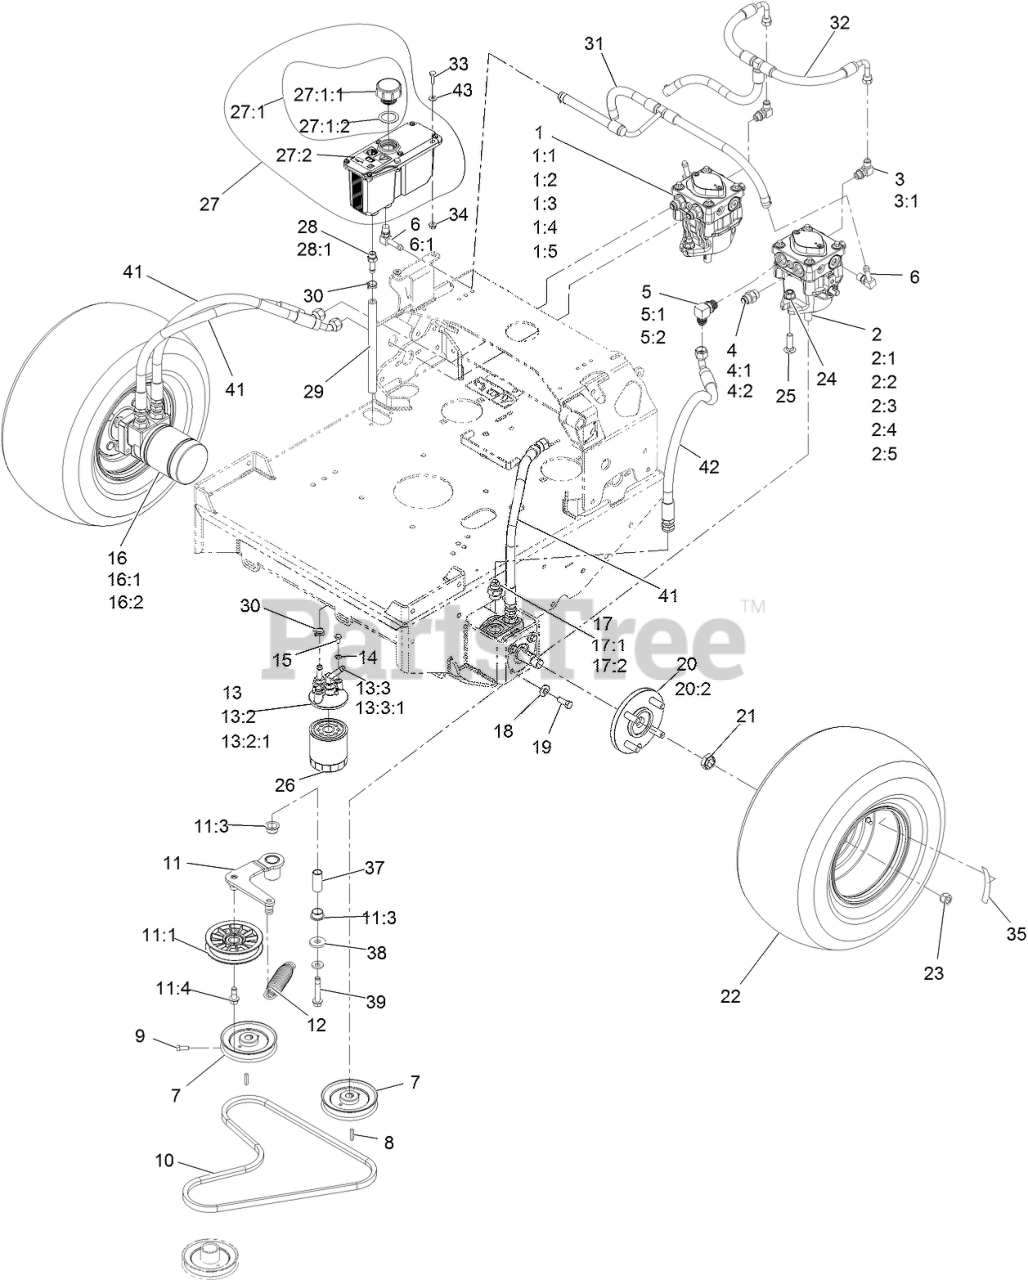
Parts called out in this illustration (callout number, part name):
1	PUMP-HYD PE RH TTH
1:1	INPUT SHAFT KIT
1:2	BEARING-THRUST
1:3	CYLINDER BLOCK KIT
1:4	SEAL OVERHAUL KIT
1:5	KIT, 10CC PUMP KIT
2	PUMP-HYD PE LH TTH
2:1	INPUT SHAFT KIT
2:2	BEARING-THRUST
2:3	CYLINDER BLOCK KIT
2:4	SEAL OVERHAUL KIT
2:5	KIT, 10CC PUMP KIT
3	FITTING-ELBOW, 90 DEG
3:1	O-RING
4	FITTING-STRAIGHT
5	FITTING-90 DEG
6	FITTING-ELBOW, 90
6:1	O-RING
7	SHEAVE ASM
9	SCREW-SET, SQH
10	BELT
11	ASM, PUMP IDLER
11:1	PULLEY-IDLER, FLAT
11:3	BUSHING-FLANGE
11:4	SCREW-HFH
12	SPRING-EXTENSION
13	ASM, FILTER HEAD
13:2	ADAPTER-STRAIGHT
13:2:1	O-RING
13:3	FITTING-BARBED, 45 DEG
13:3:1	O-RING
14	WASHER-LOCK
15	SCREW-HH
16	HYD MOTOR ASM
16:1	SEAL KIT
16:2	BEARING AND SEAL KIT
17	FITTING-STRAIGHT
17:1	O-RING
18	WASHER-BELLEVILLE
19	SCREW-HH
20	WHEEL HUB ASM
20:2	STUD-WHEEL
21	NUT-LOCK
22	ASM, DRIVE TIRE
23	NUT-LUG
24	NUT-HF, NI
25	BOLT-CARR
26	FILTER-25 MICRON, BI-DIRE
27:1	Reservoir-HYD
27:1:1	Cap-Reservoir, HYD
27:1:2	GASKET-CAP
27:2	DECAL-WARNING
28	ADAPTER-STRAIGHT
28:1	O-RING
29	HOSE-CHARGE
30	CLAMP-HOSE
31	HOSE, CASE
32	HOSE, CHARGE
33	SCREW-HH
34	NUT-HHF
35	DECAL-TORQUE WHEEL LUG-HU
37	PIVOT, IDLER
39	SCREW-HHF W/ PATCH
41	HOSE,HYDRAULIC W/COVER
42	HYD HOSE ASM
43	WASHER-FLAT
